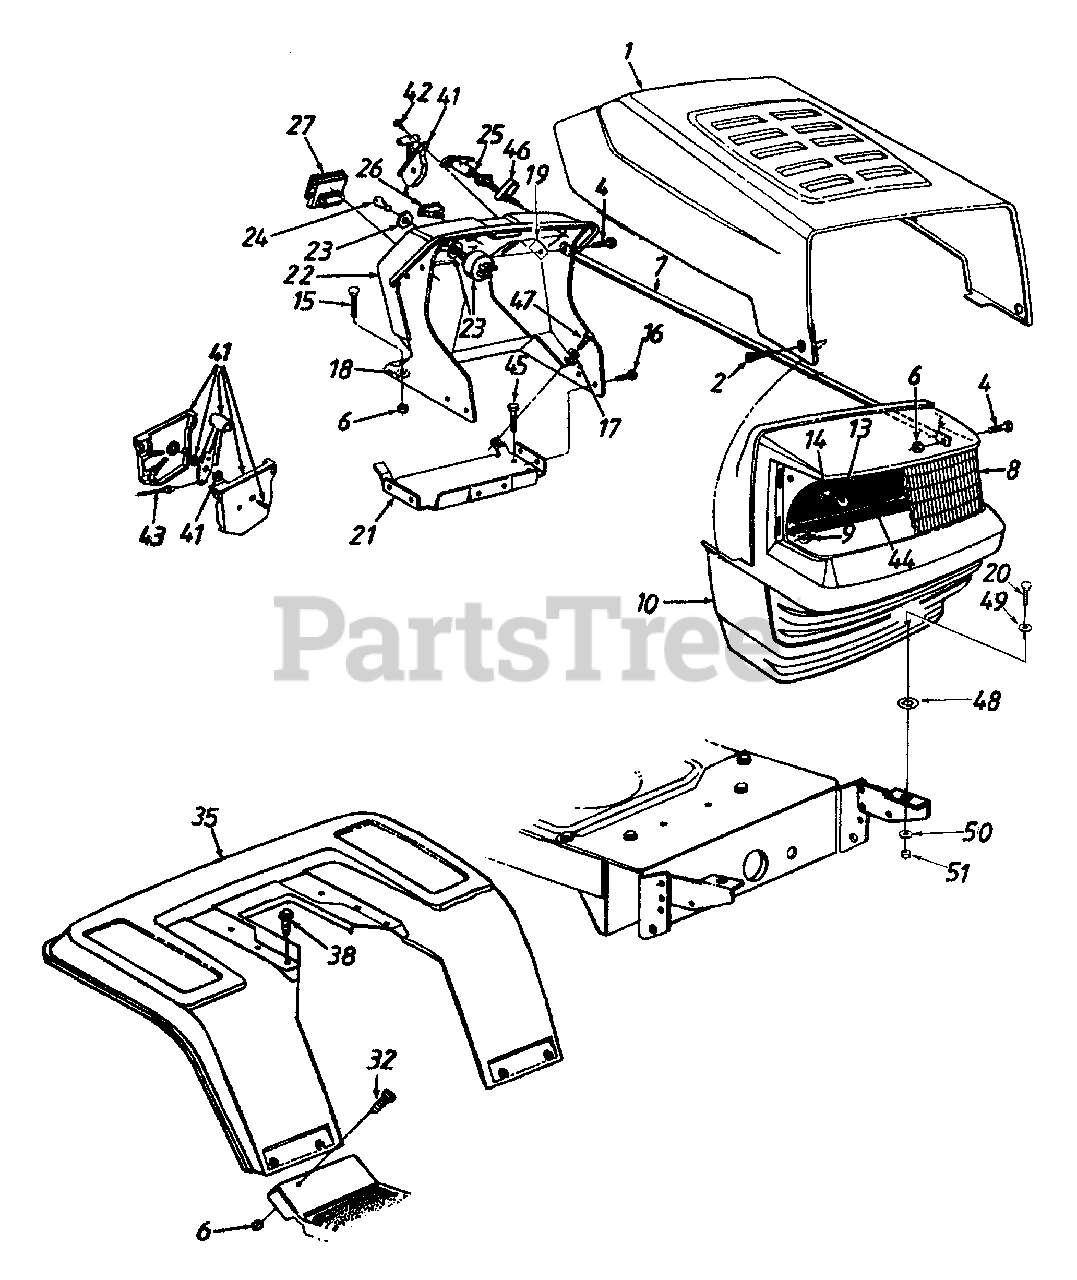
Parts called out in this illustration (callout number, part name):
4	Pan Hd. Scr. 1/4-20 x .75" Lg.
6	Hex Sems Nut 1/4-20 Thd.
8	Headlight Lens w/o Logo
9	Flange Lock Nut 1/4-20 Thd.
10	Grille
13	Lamp
14	Socket
15	Carriage Bolt 1/4-20 x .75" Lg.
16	Hex Wash. Hd. TT-Tap Scr. 1/4-20 x .5"
17	Flat Washer .281" I.D. x .73" O.D.
18	Bolt Retainer 1/4" I.D.
19	Speed Nut 1/4-20 Thd.
20	Hex Bolt 5/16-18 x .75" Lg. (Gr.5)
23	Ignition Switch
24	Ignition Key
25	Choke Control 23" Lg.
26	Light Switch
27	Ammeter
32	Truss Mach. Scr. 1/4-20 x .5" Lg.
41	Throttle Box Assembly
42	Truss Mach. AB-Tap Scr. #10 x .5" Lg.
43	Throttle Control Wire 18.5" Lg.
44	Grille Reflector Label
45	Hex Wash. Hd. B-Tap Scr. 5/16-18 x .5"
46	Choke Retainer
47	Hex TT-Tap Scr. 1/4-20 x .75" Lg.
48	U-Nut 5/16-18 Thd.
49	Flat Washer .34" I.D. x 1" O.D.
50	Lock Washer 5/16" I.D.
51	Hex Nut 5/16-18 Thd. (Gr.5)
